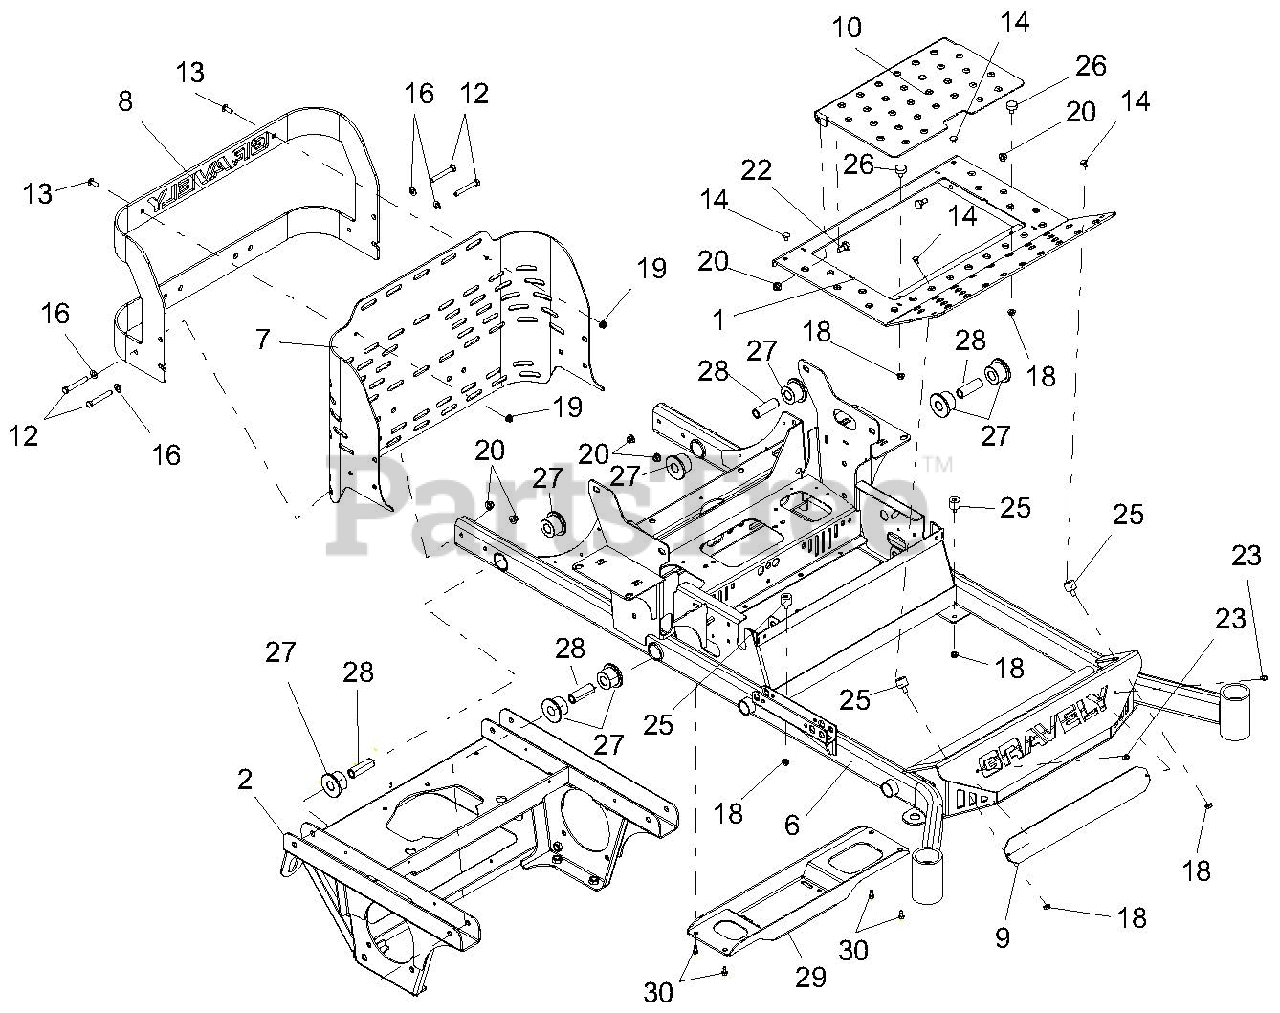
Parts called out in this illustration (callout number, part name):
1	WLDMT, FOOT PLATE
2	WLDMT, 200PT AXLE/ENGINE FRAME
3	HOSE, HYD .38-11-OK M6N0-M6N0
6	WLDMT, PT400 MAIN FRAME
6	WLDMT, 72in MAIN FRAME
7	GUARD, REAR BUMPER FINGER
8	BUMPER, PT400 REAR
9	PLATE, BUMPER LOGO BACKING
10	PANEL, INSPECTION
12	BLT-HEX .38-16X2.75 GR5 YWZC
13	BLT-RDHDSQSHNK .31-18X1.00 G5YWZC
14	BLT-RDHDSQNK .31-18X.50 G5 YWZC
16	WSHR-FL-STL.406X.812X.065 YWZ
18	NUT-SPNLK-FLG .312-18 YWZC
19	NUT-LK-NYL-FLG .31-18 YWZC
20	NUT-LK-NYL-FLG .38-16 YWZC
22	BLT, SHLDR EP .38-16X.30 HEX YZ
23	SCR-TAP .25-20X.50 HWH TR YWZ
25	BUMPER, STUD MOUNTED W/FEMALE INSERT
26	BUMPER, RUBBER
27	BUSHING, FLANGE .75X1.51X1.13X2.0 URE
28	BUSHING, SHEAVE .50X.75X2.23
29	PT400 GAS BATTERY TRAY
30	SCR-TAP .38-16X.75 HWH
